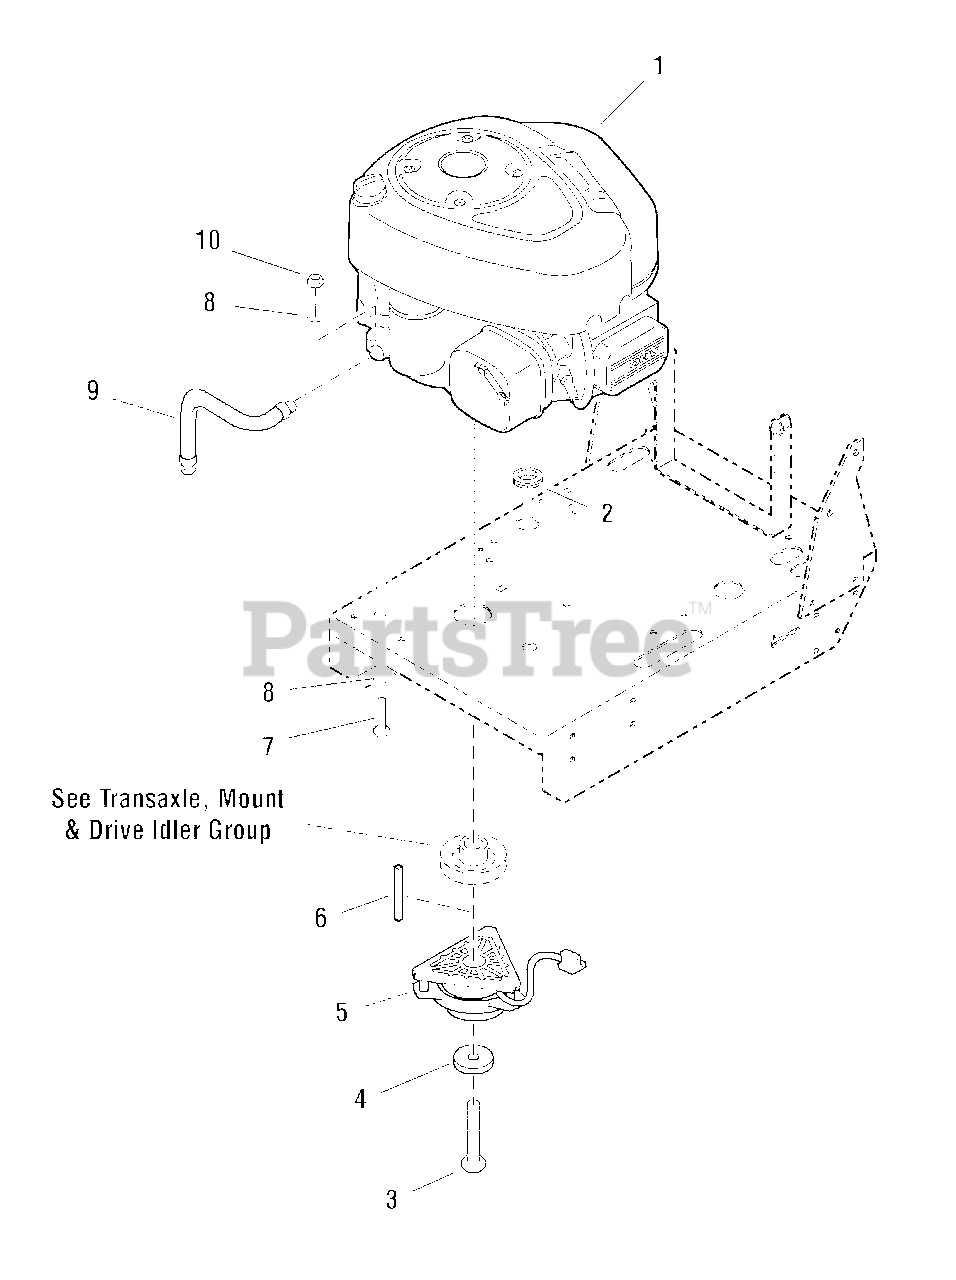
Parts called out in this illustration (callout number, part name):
1	ENGINE, 13HP Briggs & Stratton, Model 28
3	CRANKSHAFT BOLT, 7/16 x 2-3/4
4	CLUTCH RETAINER
5	ELECTRIC CLUTCH
6	KEY, 1/4 Sq. x 2
7	CAPSCREW, Hex Head, 5/16-18 x 2-1/2
8	WASHER, 5/16
9	OIL DRAIN HOSE
10	NUT, Hex Nylon Lock, 5/16-18
